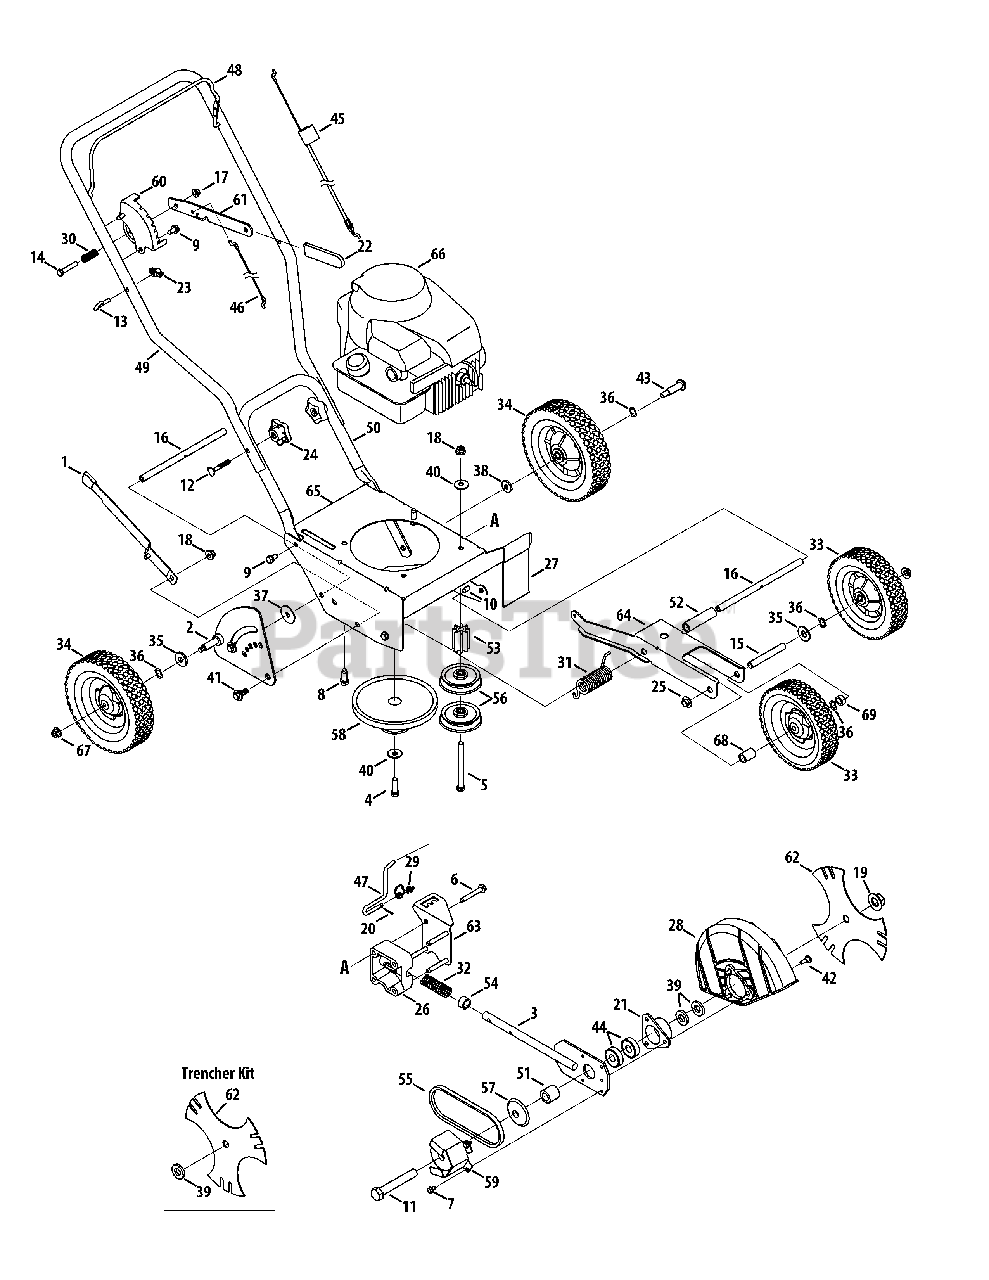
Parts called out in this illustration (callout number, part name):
1	Curb Height Adjustment Lever
2	Curb Height Adjuster Plate
3	Blade Plate Assembly
4	Screw 3/8-24
5	Screw 3/8-16
6	Hex Screw, 5/16-18
7	Self-tapping Screw, 1/4-20
8	Screw, 3/8-16
9	Hex Screw, 5/16-12
10	Hex Screw 5/16-18
11	Hex Screw, 5/8-18
12	Carriage Bolt, 5/16-18
13	Rope Guide (Eye Bolt)
14	Hex Screw, 5/16-18
15	Axle Shaft .50x6.65
16	Frame Spacer .50x9.25
17	Lock Flange Nut, 5/16-18
18	Flange Nut 3/8-16
19	Flange Nut, 5/8-18
20	Clevis Pin 3/32 x .625
21	Bearing Cup
23	Wing Nut
24	Star Knob
25	Push Cap 1/2" rod
26	Bearing Block
27	Debris Guard
28	Blade Guard
29	Double Torsion Spring
30	Compression Spring
31	Torsion Spring
32	Compression Spring
33	Wheel 7 x 1.75 T-Tread
34	Wheel 8 x 1.75 T-Tread
35	Flat Washer, .531 x 1.25 x .181
36	Wave Washer .531 x .781 x .013
37	Flat Washer, .385 x 1.5 x .075
38	Flat Washer .385 x 1.0 x .135 †
39	Flat Washer .635x1.24x.181
40	Bell Washer,.396 x 1.140
41	Shoulder Screw, 3/8-16
42	Shoulder Screw
43	Shoulder Screw, 3/8-16
44	Bearing, .625 ID x 1.57 OD
45	Control Cable (Briggs & Stratton)
46	Wheel Adjustment Cable
47	Blade Adjustment Rod
48	Bail Handle
49	Upper Handle
50	Lower Handle
51	Spacer, .63 x 1.12 x 1.06
52	Spacer
53	Pulley Mount Spacer
54	Spacer, .64 x.88 x .50
56	Flat Idler Pulley, 2.5 OD
57	Sheave
58	Combination Flywheel Pulley
59	Belt Guard
61	Depth Index Lever
62	Tri-Star Blade
63	Bracket Plate
64	Wheel Bracket
66	Replacement Engine
67	Flange Lock Nut, 3/8-16
68	Spacer., .525 x .775 x .93
69	Spacer., .505ID x .88OD x .440
